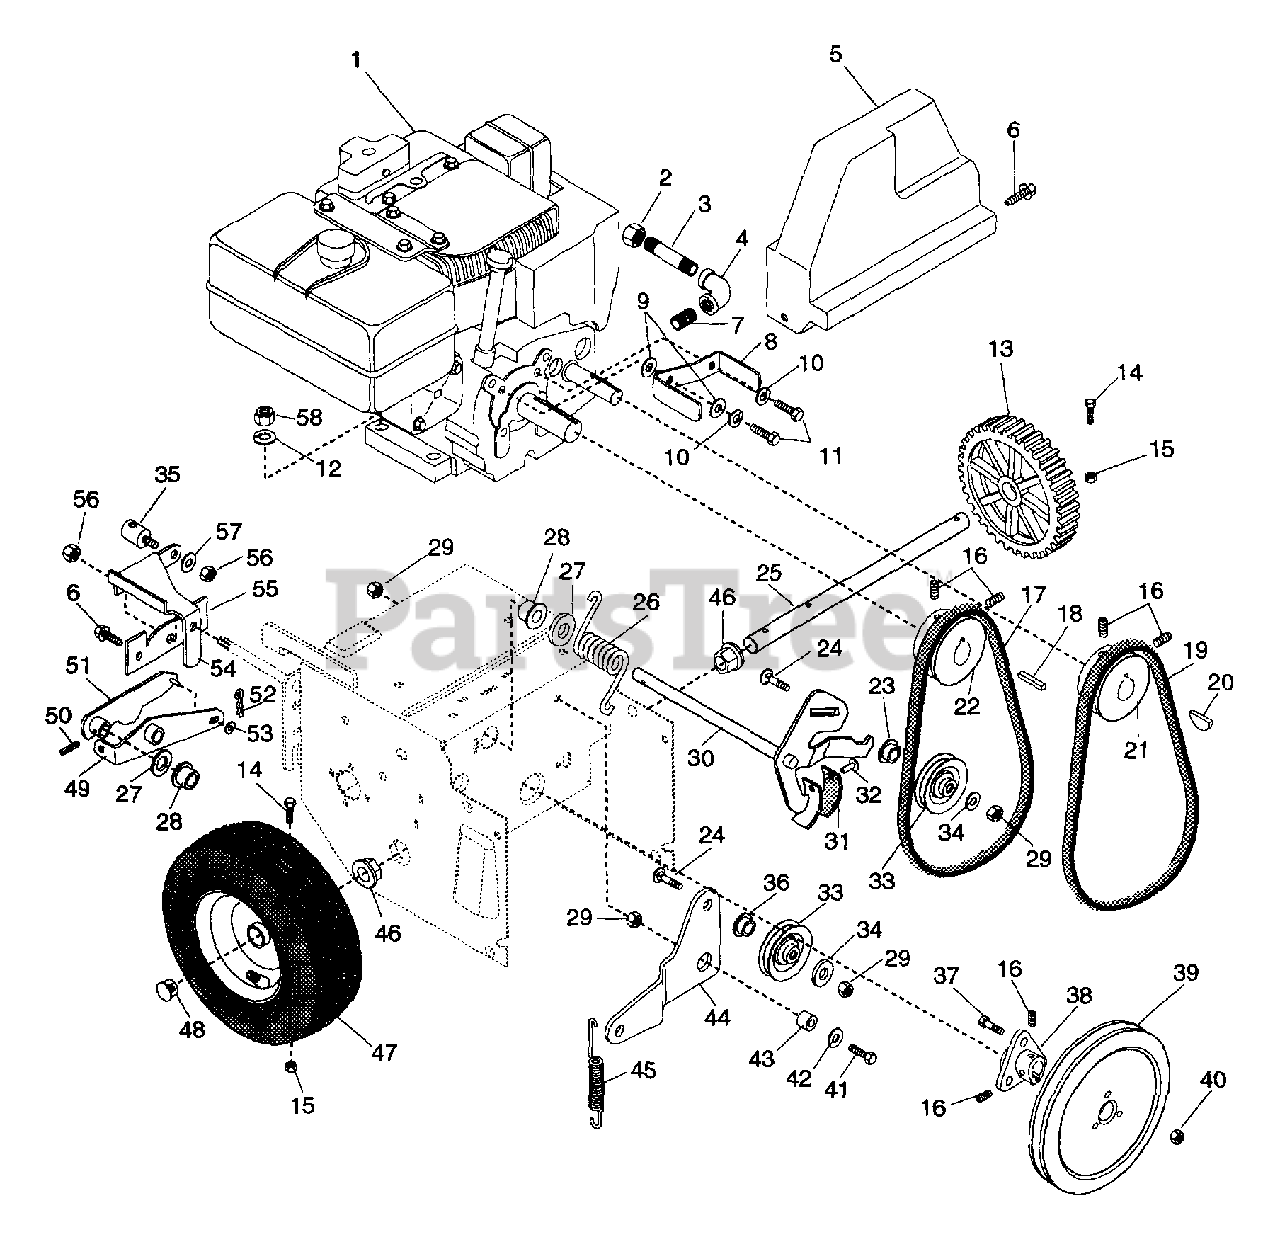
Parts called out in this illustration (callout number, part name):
1	ENGINE-HSSK 50 TEC W/PTO
1	ENGINE-7 HP TEC W/PTO
2	HEX CAP
4	STREET ELBOW
4	ELBOW 90 1/4-18 NPTF
5	BELT COVER
6	SCR-TAP .250-20X.37 HWH PL TR
7	NIPPLE
8	BELT FINGER
9	WSHR-FL-STL .380X.875X.179 PL
10	WSHR-LK .313X.093 MED HICLR
11	BLT-HEX .31-24X.75 PL GR5
12	WSHR-LK .312X.097 PL HVY
14	BLT-HEX .25-20X2.25 PL GR8
15	NUT-LK TOP .250-20 PL
16	SCR-SET .32-18X.38 SKHCUPNL OH
17	BELT,4L TO BE REPLACED07200021
17	V-BELT, 4L-RAW EDGE
18	KEY-SQ .188X1.0X.188 SAE 8630
19	V-BELT, 3L-COGGED
20	KEY-WDRF .125X.625X.250 SAE5
21	SHEAVE CAMSHAFT
21	SHEAVE-CAMSHAFT
22	HUB
23	SPCR, BRG .315X.50X.688X.281
24	BLT-RDHDSQNK .31-18X1.38SHT PL
25	AXLE SHAFT
26	SG-TORS .148X1.0X1.53
27	WSHR-FL-STL .531X1.062X.095 PL
28	BSHG-FLG.500X.625X.312X.750NY
29	NUT-LK .312-18 GR A PL
30	CLUTCH ARM W/BRAKE PAD
31	BRAKE LINING
32	RVT-TBLR .187X.437 RH ST PL
33	IDLER
34	WSHR-FL-STL .38X.875X.083 PL
36	BSHG, FLG .325X.499X.26X.88
37	BLT-SERRDHD SL .31-18X.75 YZ
39	PLY-V 8.0 X 1.25 3BLT SALEM
40	NUT-FLG. .312-18 PL
41	BLT-HEX .31-18X.63 PL GR 2
42	WSHR-FL-STL .344X1.375X.075 PL
43	SPACER BUSHING .5 X .32 X .163
44	IDLER ARM
45	SG-TENS .047X.44X3.37 WLD 1.47
46	BSHG-FLG .750X.873X.640X.900HX
47	WHL-COMP 3.5 X 6
47	TIRE
47	T/WHL ASSY
48	HOLE PLUG
49	SPRING LEVER WELDMENT
50	PIN-ROLL .156X.88
52	PIN-HAIR INT .08X.18X1.18
53	WSHR-FL-STL .268X.562X.046 PL
54	BELLCRANK
56	NUT-LK-CTR .375-16 GR A PL
57	WSHR-FL-STL .382X.812X.062
58	NUT-HEX .312-18
